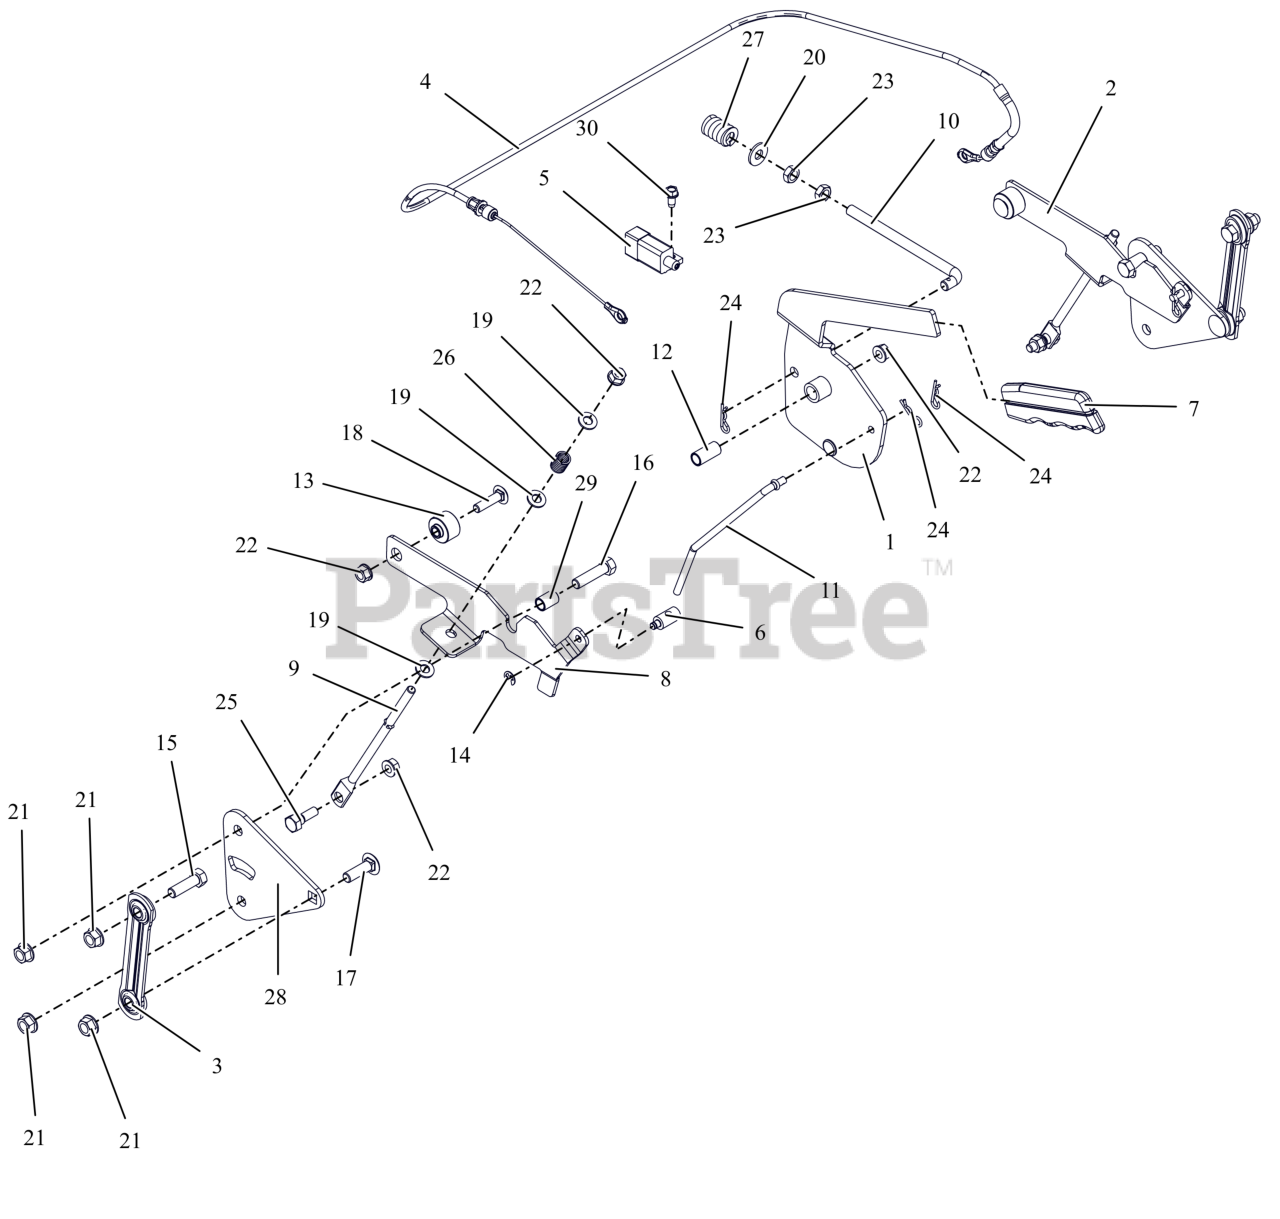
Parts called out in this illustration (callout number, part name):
1	LEVER, PARKING BRAKE
2	ARM, BRAKE - LH (W/PIN)
3	LINK, STAMPED STEERING
4	CABLE, BRAKE - PARKING
5	SWITCH-BRAKE NO/NO-POST & HOLE
6	TRUNION, 1/4-20
7	GRIP, PARKING (GRAY)
8	ARM, BRAKE - RH
9	ROD, LINK - TRANSMISSION BRAKE
10	ROD, OVER CENTER
11	ROD, BRAKE LINK
12	BSHG-SLV .385X.500X1.045
13	SPCR, FLANGE
14	RG-RTNG-EXT .250X.025
15	BLT, HEX .38-16X1.25 G5 ZCC
16	BLT, HEX .38-16X1.50 G5 ZCC
17	BLT,RHSSN .38-16X1.25 G5 ZCC
18	BTL,RHSSN .313-18 X 1.25 G5 ZCC
19	WSHR,FLT .344X.688X.065 ZCC
20	WSHR,FLT .375X.875X.083 ZCC
21	NUT-LK-TOP-FLG .38-16 ZC120
22	NUT-LK-TOP-FLG .312-18 GF ZCC
23	NUT-JAM .375-16 G2 ZCC
24	PIN, HAIR #213 .08X1.19 ZCC
25	BOLT,SHLDR .38X.25 -.31-18X.75
26	SPRING, COMPRESSION
27	SG-COMP .187X.56X1.62
28	PLATE, TRANSAXLE (BLACK)
29	SPCR SLEEVED .385X.500X.718
30	SCR-TAP .25-20X.50 HWH ZCC
